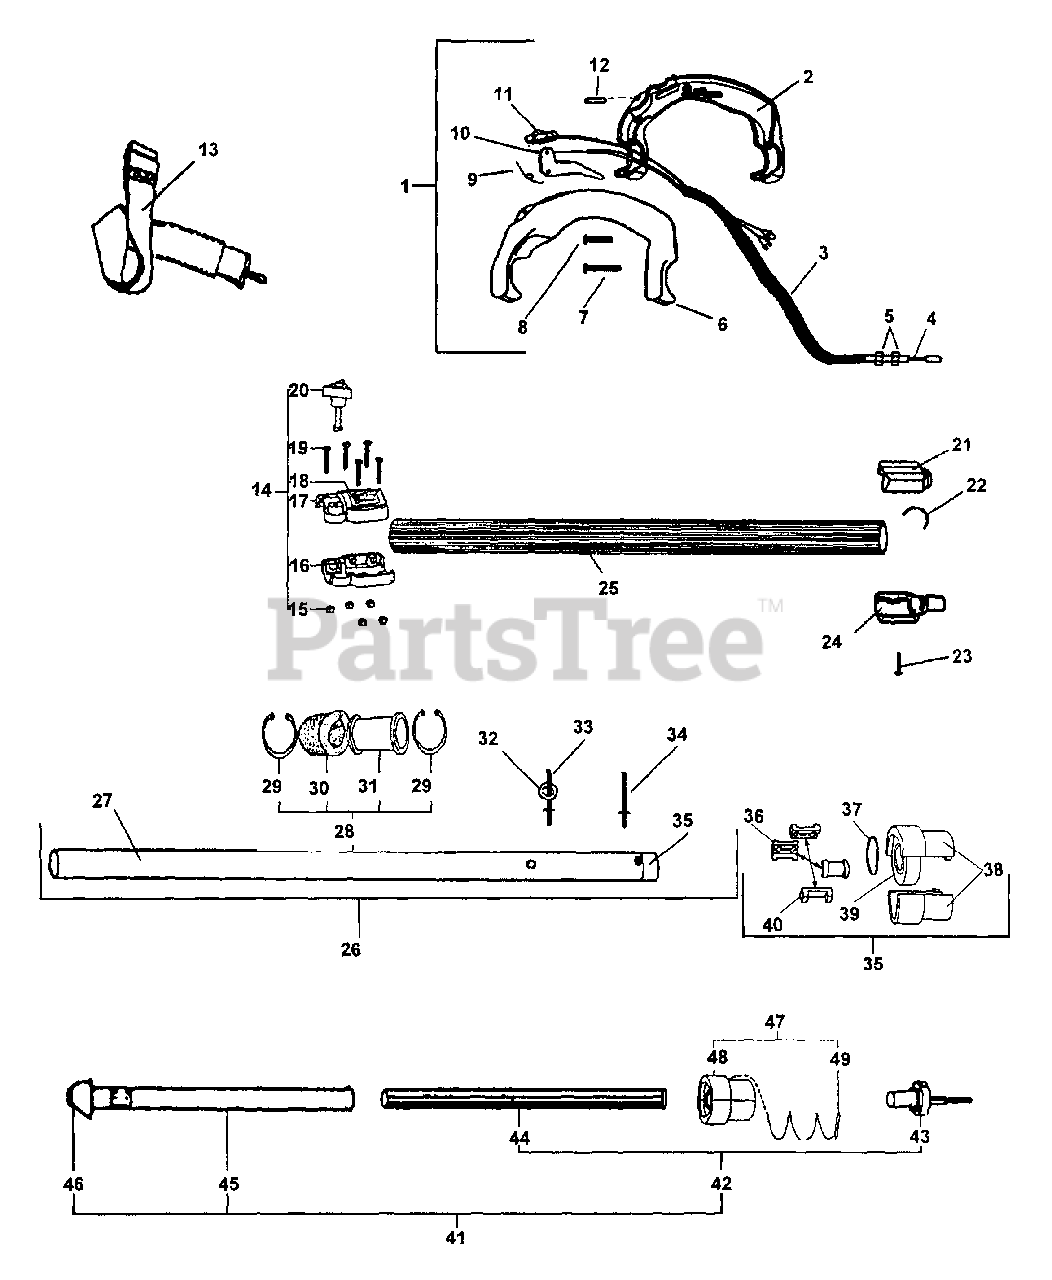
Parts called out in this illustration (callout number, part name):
1	HANDLE ASSY - REAR
2	HANDLE, REAR - RIGHT
3	TUBE, PROTECTIVE - CORRUGATED
4	CABLE, THROTTLE
6	HANDLE, REAR - LEFT
7	SCREW - 10-24 X 1-1/4"
8	SCREW - 10-24 X 7/8"
9	SPRING, TRIGGER
10	TRIGGER, THROTTLE
11	IGNITION SWITCH ASSY
12	PIN - LOCATING
13	SHOULDER STRAP ASSY
14	COLLAR ASSY
15	LOCKNUT - 10-24
16	COLLAR, MAIN PIPE - LOWER
17	COLLAR, MAIN PIPE - UPPER
18	LABEL - CAUTION
19	SCREW - 10-24 X 1-1/4"
20	THUMBSCREW
21	LOWER HSNG ADAPT (TOP)
23	SCREW - 10-24 X 1-1/4"
24	ADAPTER - LOWER
25	PIPE, MAIN - ORANGE
26	MAIN PIPE ASSY
27	MAIN PIPE ASSY - BLACK
28	DRIVESHAFT GUIDE ASSY
29	RING, RETAINING
30	PAD, FOAM
31	GUIDE, DRIVESHAFT
32	WASHER - 5
35	BEARING HOLDER KIT
36	HOLDER, INNER BEARING - SMALL
37	WASHER - SPRING
38	BEARING HOLDER KIT
39	BEARING, BALL - 6002
40	HOLDER, INNER BEARING - LARGE
41	DRIVESHAFT ASSY
42	DRIVESHAFT - LOWER
43	CONNECTOR, SHAFT
44	DRIVESHAFT - LOWER
45	DRIVESHAFT - UPPER
46	ADAPTER, DRIVESHAFT - UPPER
47	FLOATING BUSHING ASSY
48	BUSHING, FLOATING
